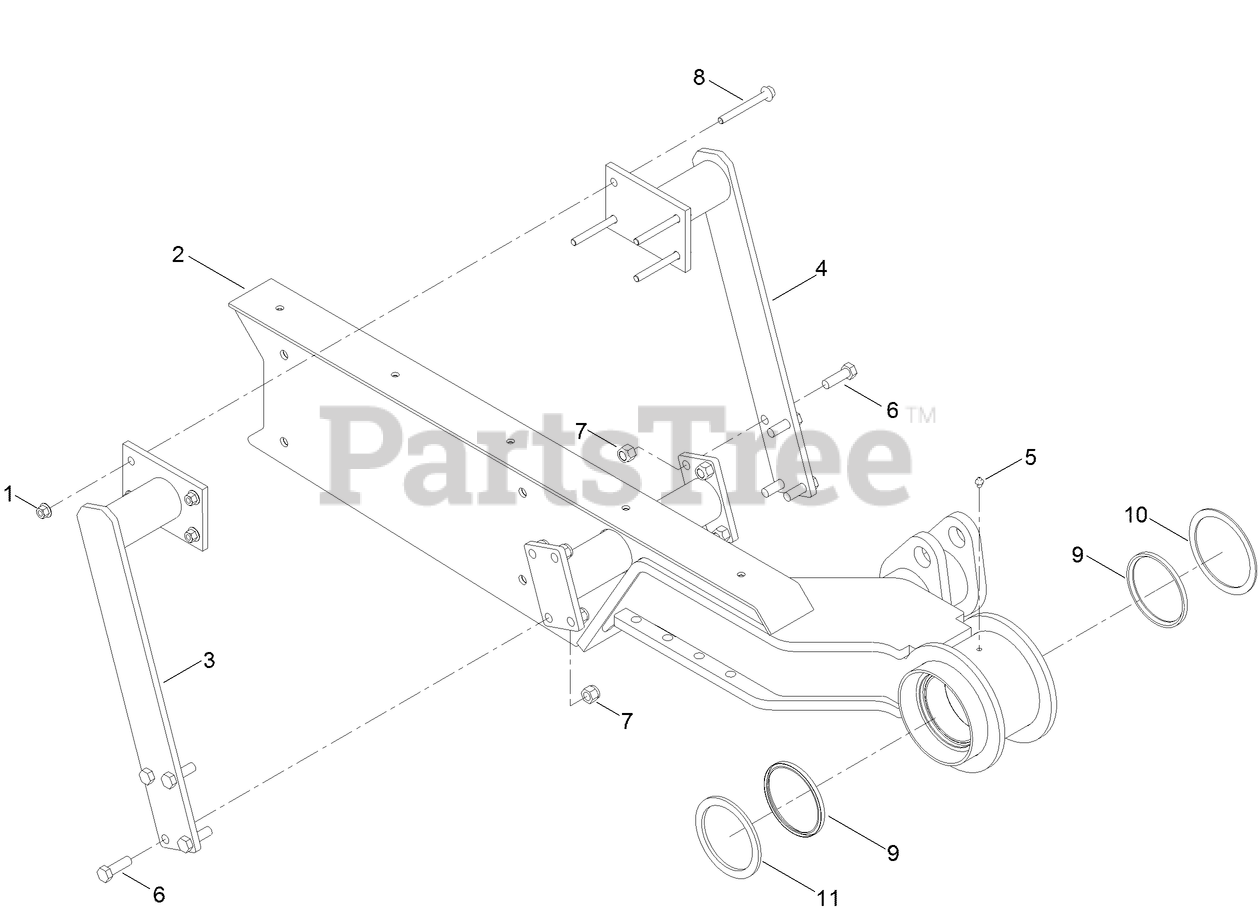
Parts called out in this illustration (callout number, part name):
1	NUT-LOCK, HHF
2	DIRECT DRIVE BOOM ASM
3	MOUNT-CRUMBER, LEFT
4	MOUNT-CRUMBER, RIGHT
5	FITTING-GREASE
6	SCREW-HH
7	NUT-LOCK, NI
8	BOLT-HHF
9	SEAL-Urethane
10	WASHER-THRUST, THIN
11	WASHER-THRUST, THICK
